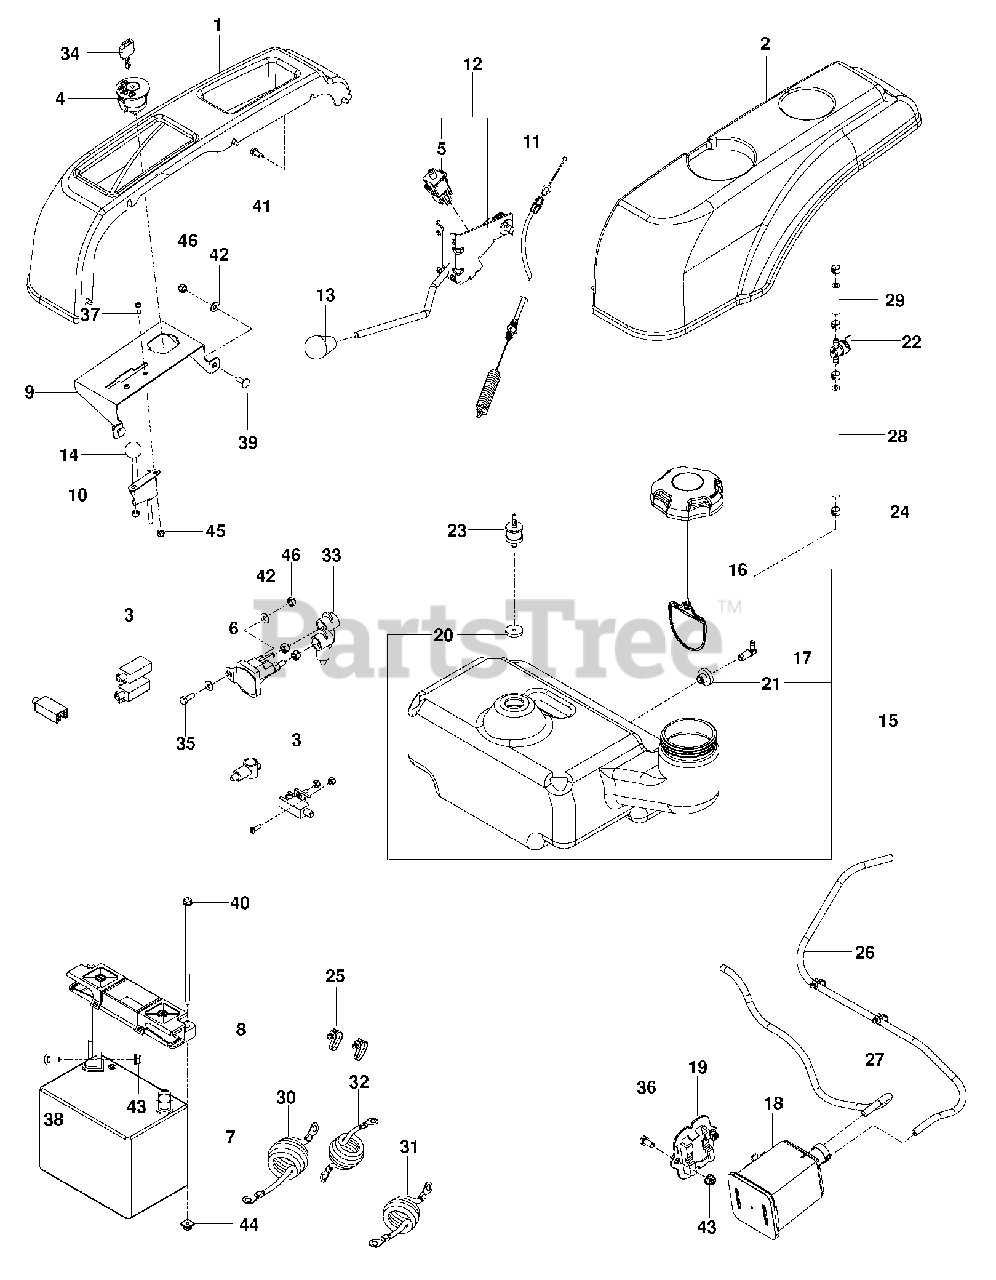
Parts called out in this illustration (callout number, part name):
1	FENDER, RZ 30/38 RT
2	FENDER, RZ 30/38 LT
3	SWITCH INTERLOCKT
4	RP IGNITION SWITCH
5	SWITCH INTERLOCK
6	SOLENOID.W/BRASS.PLUNGER
7	BATTERY, 12 V 330 AMP
8	BATTERY HOLD DOWN
9	MOUNT, CONTROLS, BLK
10	CABLE.THROTTLE.20"
11	CABLE-CLUTCH ENGAGE
12	CLUTCH.ENGAGE.ASSEM.W/CABLE
13	KNOB - SHIFT
14	KNOB.ROUND.BALL.BLACK
15	FUEL TANK ASM SMALL
16	CAP, FUEL
17	STEM, FUEL TANK
18	CANNISTER, CARBON
19	BRACKET, CANISTER
20	GROMMET, CHECK VALVE
21	RUBBER GROMMET
22	FUEL VALVE
23	VALVE.FUEL.CHECK
24	HOSE CLAMP
25	TIE WRAP, 8-3/8", W/CLIP
26	HOSE, VAPOR 3/16 X 39"
27	HOSE, FUEL, 3/16" X 20"
28	HOSE 1/4 X 8
29	HOSE 1/4 X 2"
30	POST.CABLE LONG
31	CABLE POSITIVE, LONG
32	BATTERY CABLE, NEGATIVE
33	TERMINAL COVER-SM
34	KEY
35	HCS 1/4C X 3/4 HCS
36	HCS 5/16-18 X 5/8 GR 5 ZD
37	SCREW #10-24 X 5/8
38	BOLT 5/16-18 X3/4 ZN/YEL GR 5
39	BOLT
40	BOLT 1/4-20 X 7.5
41	SCREW 1/4 X 5/8
42	WASHER 1/4 SAE
43	5/16-18 NYLOC FLANGE NUT
44	PUSH NUT-NYLON
45	NUT 10-24 NYLOC
46	RP_NUT 1/4-20 NYLOC
